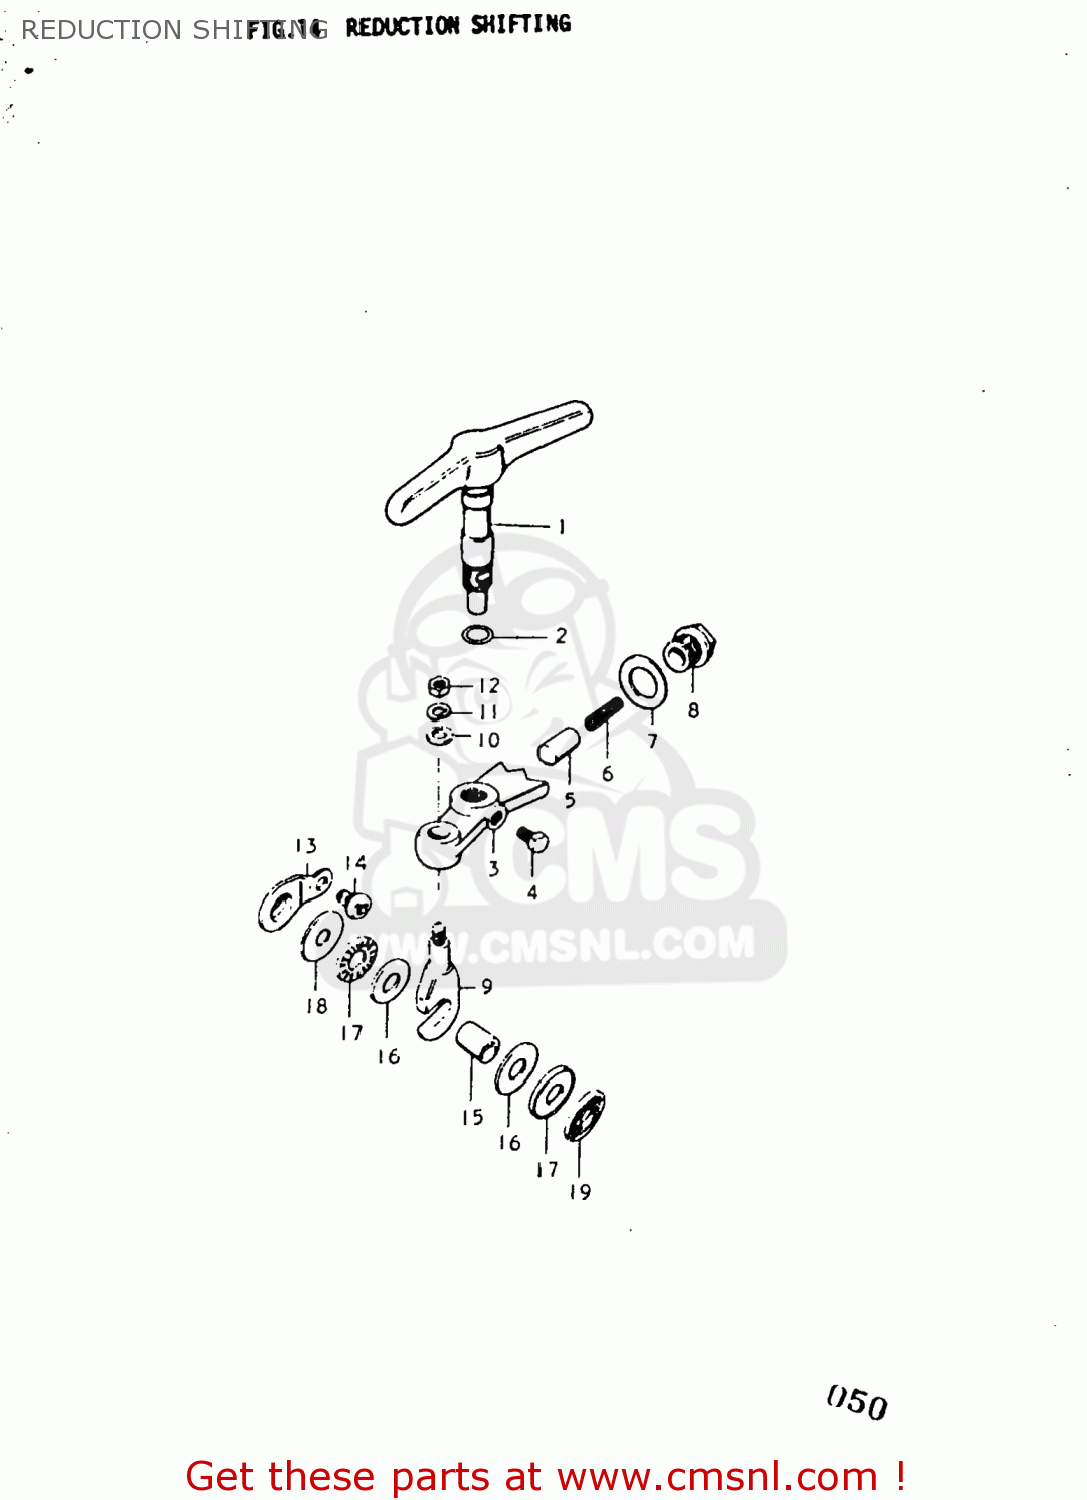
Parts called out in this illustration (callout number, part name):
1	REDUCTION SHIFTING LEVER
2	O RING(D:1.3,ID:9.6)
3	ARM,REDUCTION SHAFT
4	BOLT
5	STOPPER,GEAR SHIFTING
6	SPRING
7	WASHER (16.5X42X2.6)
8	HOLDER,SHIFTING CAM STOPPER
9	REDUCTION SHIFTING ARM PIN
10	WASHER
11	LOCK WASHER
12	NUT
13	REDUCTION ROD DUST SEAL
14	SCREW
15	SPACER(6X10X12.2)
16	WASHER(10.1X21.4X0.8)
17	BEARING(10X22X2.8)
18	WASHER
19	WASHER (6X22X2)
